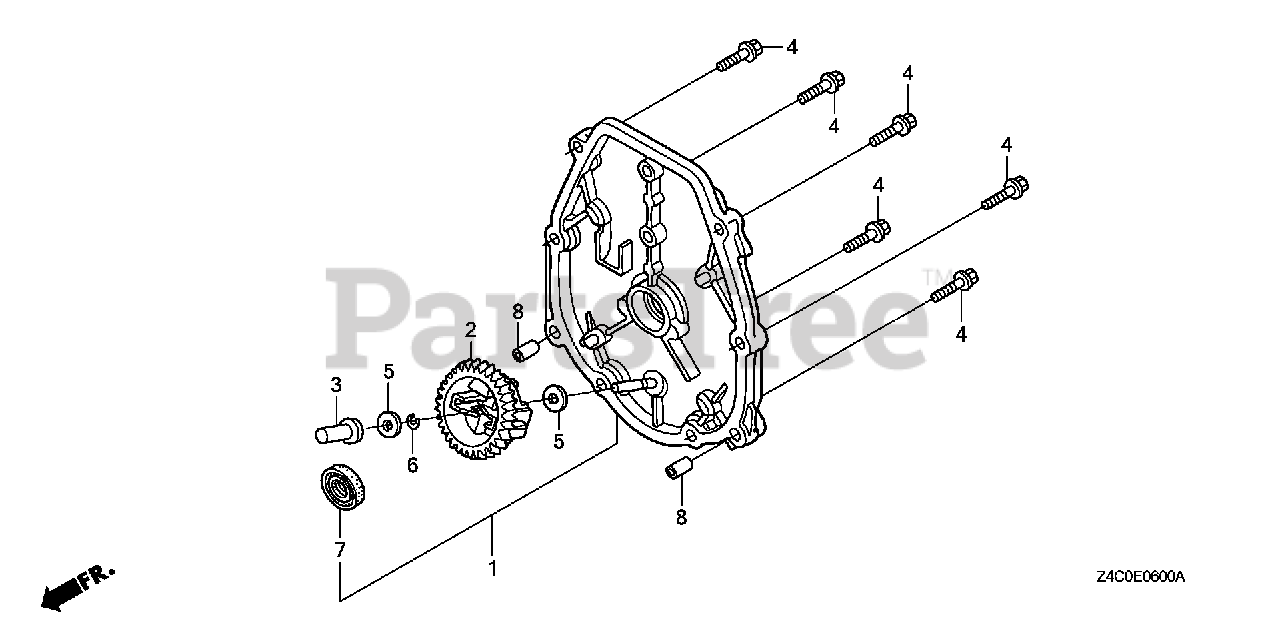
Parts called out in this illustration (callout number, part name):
1	COVER, CRANKCASE SIDE
2	GOVERNOR ASSY.
3	SLIDER, GOVERNOR
4	BOLT, FLANGE (5X23)
5	WASHER (4.2X13)
6	CLIP, GOVERNOR HOLDER
7	OIL SEAL (17X27X5) (KOYO)
8	PIN, DOWEL (6X10)
